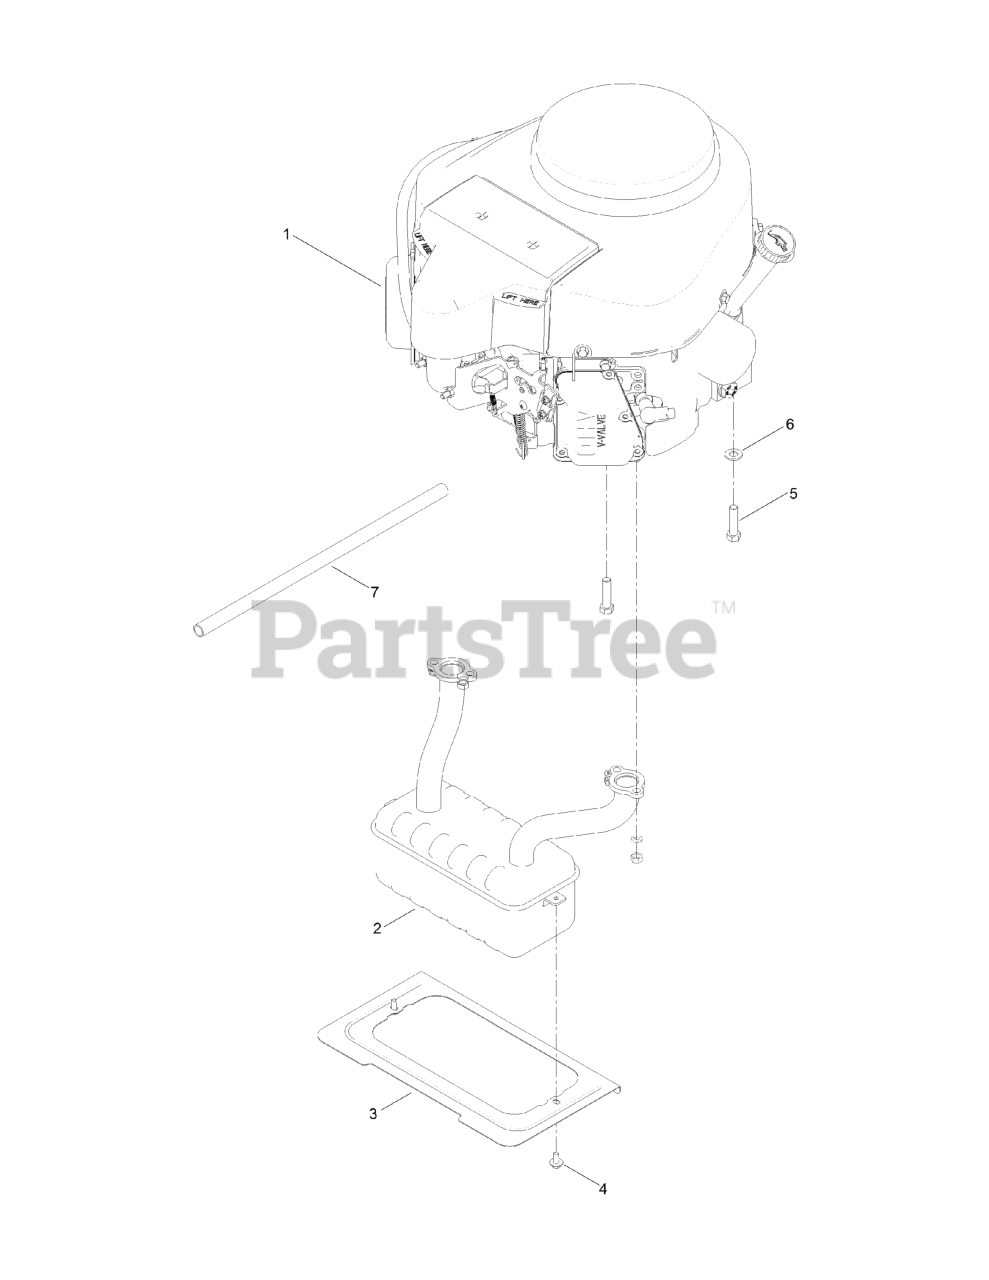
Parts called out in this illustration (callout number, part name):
2	Muffler
3	SHIELD-HEAT
4	SCREW-HHFTF
5	BOLT-HH
6	WASHER-FLAT
7	TUBE-DRAIN, OIL
